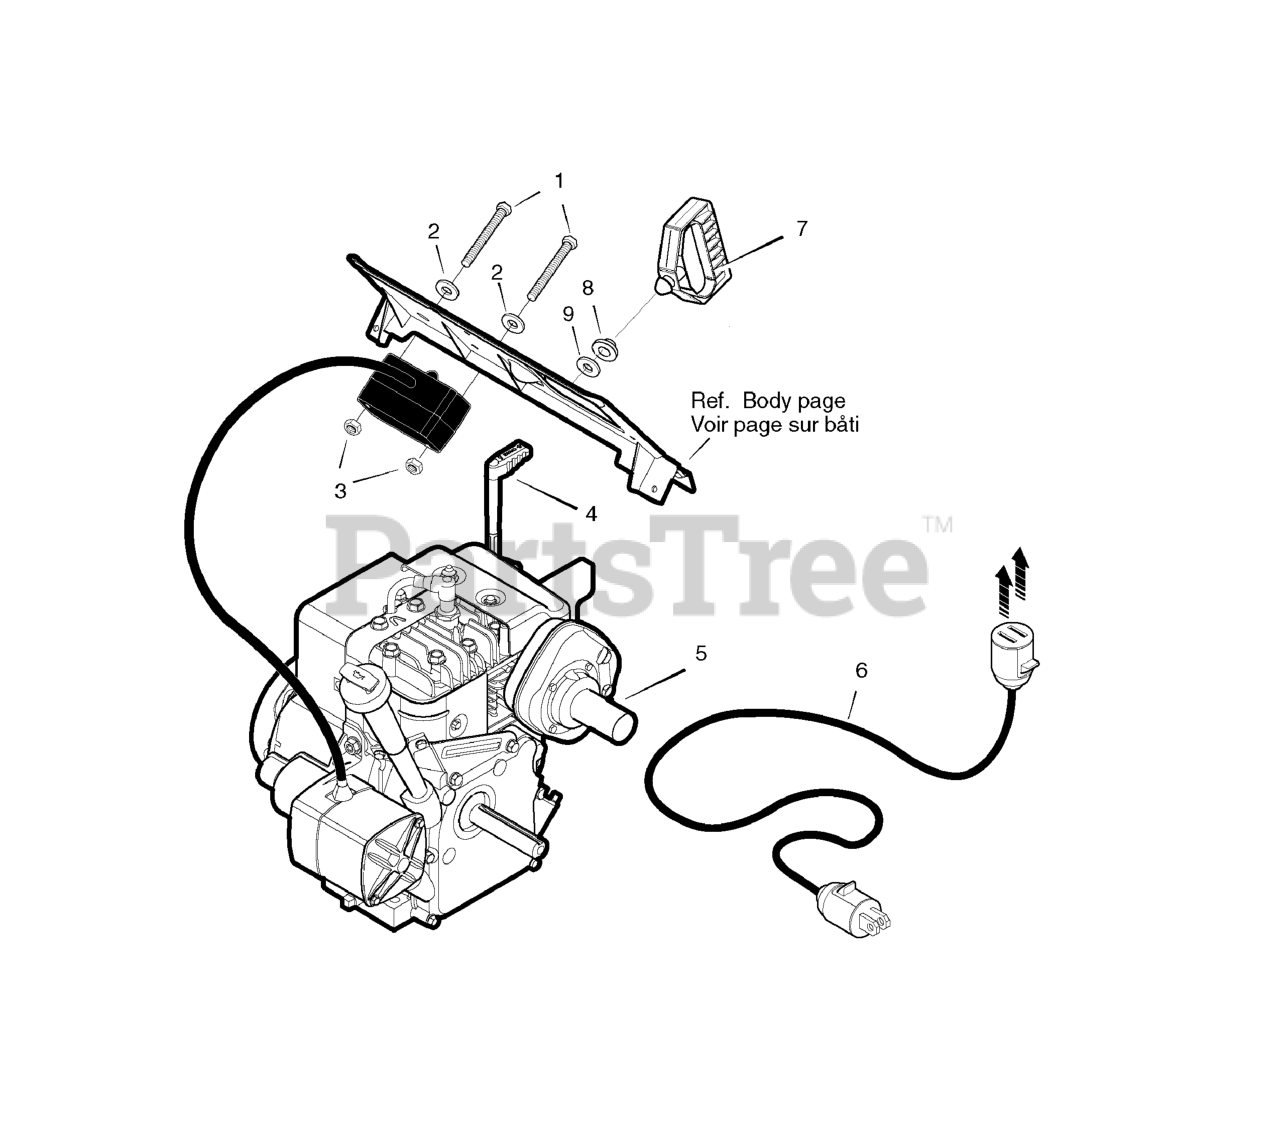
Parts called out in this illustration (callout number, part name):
1	Screw, No. 8-32 x 3.00
3	Nut, Keps No. 8
4	Lever, Choke
5-1	Muffler
5-2	Gasket, Muffler
5-3	Bolt, Muffler
5-4	Washer, Split Lock
5-5	Nut, Hex 5/16-18
5-6	Bolt, Hex 5/16-18
6	CORD, Electric, 10FT. 110V
7	GRIP, Starter Rope
8	Grommet, Rope
9	Washer
